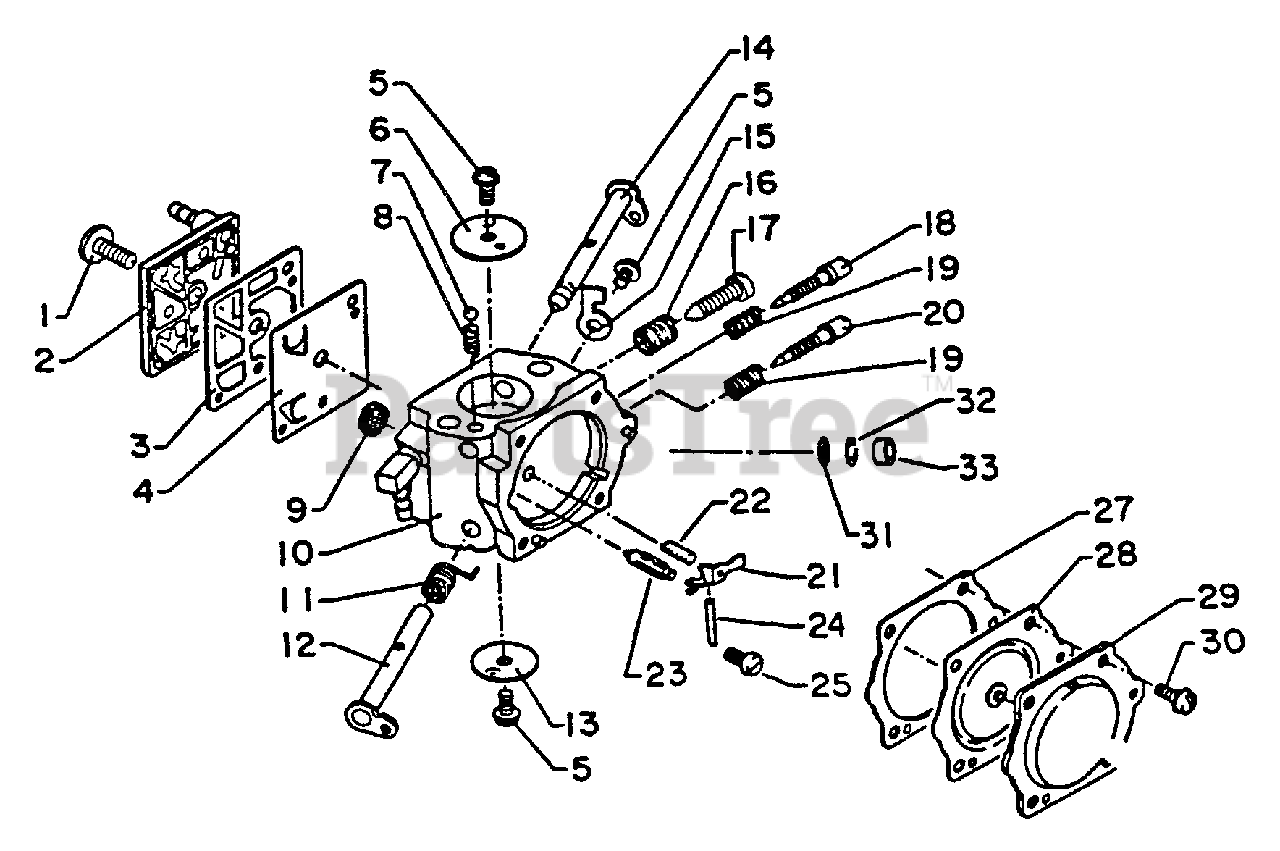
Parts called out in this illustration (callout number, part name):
2	COVER, PUMP
3	GASKET, FUEL PUMP
4	DIAPHRAGM, FUEL PUMP
6	VALVE, THROTTLE
7	BALL, CHOKE FRICTION
9	SCREEN, FUEL INLET
10	BODY, CARBURETOR
11	SPRING, THROTTLE
12	SHAFT, THROTTLE
13	VALVE, THROTTLE
14	SHAFT, CHOKE
15	STOP, THROTTLE
16	SPRING, IDLE ADJUST
17	SCREW, IDLE ADJUST
18	NEEDLE, LOW SPEED
19	SPRING, NEEDLE
20	NEEDLE, HIGH SPEED
21	LEVER, METERING
22	SPRING, METERING LEVER
23	VALVE, INLET NEEDLE
24	PIN, METERING LEVER
25	SCREW, METERING LEVER PIN
27	GASKET, METERING DIAPHRAGM
28	DIAPHRAGM, METERING
29	COVER, METERING DIAPHRAGM
31	SCREEN, SPARK ARRESTER
32	RING, RETAINING
33	PLUG, CUP
